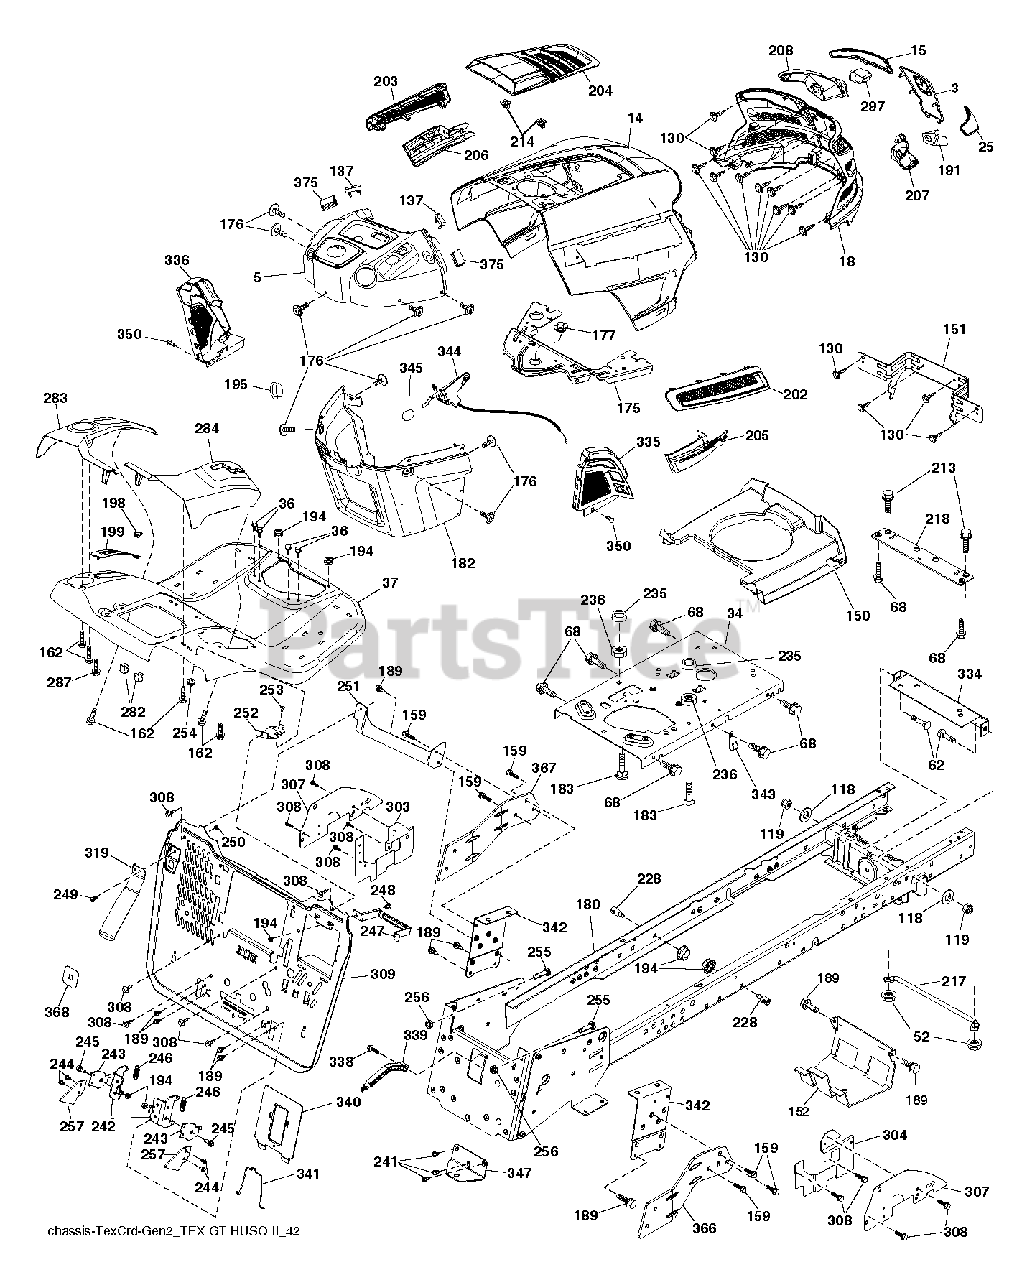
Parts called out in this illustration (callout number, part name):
3	APPLIQUE.SUBASM.GT.HUSQ.II
5	DASH.UPPER.GT2.SM.E.RS.CH.498
14	HOOD.ASM.HUSQVARNA.GT.TEX.ORAN
15	LENS.HEADLIGHT.LH.GTII.2011
18	GRILLE.SUBSTRATE.2011.
25	LENS.HEADLIGHT.RH.GTII.2011
34	PLATE.ENGINE.10GA.CRD.GENII
36	SCREW 5/16"
37	FENDER.TEX.SRD.CRD.FRN.GUARDS
52	LOCKNUT
62	BOLT D
68	SCREW LT
118	WASHER
130	SCREW.#10 X 0.750.BOS
137	BUMPER DASH
150	AIR.DUCT.GTV.BLACK
151	BRACKET.PIVOT.HOOD.GT.HUSQ.II
152	SHIELD.BROWNING.PNT.GT.V2
159	SCREW, 3/8-16X3/4
162	SCREW.HI-LO.CONSOLE
175	PLATE.CROSSMEMBER.HUSQ
176	SCREW.#10-24X5/8.RN.QU
177	BUSHING STEERING
180	WELDMENT.CHASSIS.TEX.CRD.GEN.2
182	DASH.LOWER.HUSQPREDGT
183	BOLT.5/16-18X1-1/4 FULL THD
189	SCREW
191	INSERT.REFLECTIVE.RH.HUSQ.GTII
194	NUT LOCK HEX FLANGE 5/16-18
195	PLUG.HOLE.DASH.LOWER.12V.BLK
198	INDICATOR.DECK.LIFT.RED
199	PLATE DECK LIFT
202	VENT.SIDE.RH.GT.HUSQ.II.
203	VENT.SIDE.LH.GT.HUSQ.II.498
204	VENT.TOP.HUSQ.GT2
205	SIDE.TRIM.RH.GT.HUSQ.II
206	SIDE.TRIM.LH.GT.HUSQ.II.GRAY
207	BEZEL LIGHT.RH.GT.II.MYLAR
208	BEZEL LIGHT.LH.GT.II.MYLAR
213	BOLT
214	CLIP.RETAINER.TINNER.
217	ROD.PIVOT.HOOD
218	X-PIECE.HOOD.STOP.NON/
228	STUD.FASTNER.W/ANTI-ROTATE
235	SPACER FENDER
236	NUT.CENTERLOCK.5/16-
241	SCREW 5/16-18X1
242	LATCH.BRACKET.TCRD.GEN 2.5.BAG
243	ARM.PIVOTING.TCRD.GEN2.5.BAGGE
244	SCREW
245	BOLT, SHOULDER
246	SPRING.TCRD.GEN2.5.BAGGER.EXT
247	STRAP.BATTERY.TCRD.GE
248	BOLT
249	SCREW.BUTTONHD.10-24X1/2.(2 2)
250	NUT 10-24 NYLOC
251	BRKT.TOPSPPRT.BCKPLT.
252	BRKT.TOPSPPRT.BCKPLT.RH.CRD2.5
253	BOLT
254	NUT T
255	BOLT.CROSSDRILLED.381
256	TRANSAXLE.HG.347-0510.ROS
257	LATCH.BAGGER.TEXCRD2.5
282	CLIP.RETAINER.CONSOLE.LT.HUSQ
283	CONSOLE.DECKLIFT.CRDII.498
284	CONSOLE.PEDAL.HYDRO
287	SCREW 1/4X20
297	INSERT.REFLECTIVE.LH.HUSQ.GTII
303	SHIELD.LWR.LH.LT.30"CRDSRD.PNT
304	SHIELD.LWR.RH.LT30DECK.PNT.BLK
307	SHIELD.UPPER.CRD.SRD.ISO
308	BOLT, 5/16-18 X 1 3/4
309	BACKPLATE.TEXCRD2.5.B
319	LEVER.BAG.CRDII.ANTIROTATION
334	BRACKET.ENGINE
335	COVER.LOWER.DASH.RH.BLACK
336	COVER-LH.LOWER.DASH.GT2.BLACK
338	BOLT BOLT SHOULDER
339	LEVER LEVER BAGGER
340	BATTERY.DOOR.TCRD.GEN
341	LATCH.BATTERY.DOOR.TC
342	SUPPORT SUPPORT FENDER
343	CLIP CLIP
344	CONTROL.EZ.MULCH.TEX/CRD
345	RP KNOB.OVAL.TAPERED.3/8-16BLK
347	HITCH HITCH TOW TEX CRD GEN 2
350	CLIP.X-MAS.TREE
366	BRACKET.RH.FRONT.BAGGER.BLACK
367	BRACKET.LH.FRONT.BAGGER.BLACK
368	FULL.LEVER.BAGGER.TEX.CRD
375	BUMPER CLIP-ON. DASH 1"
